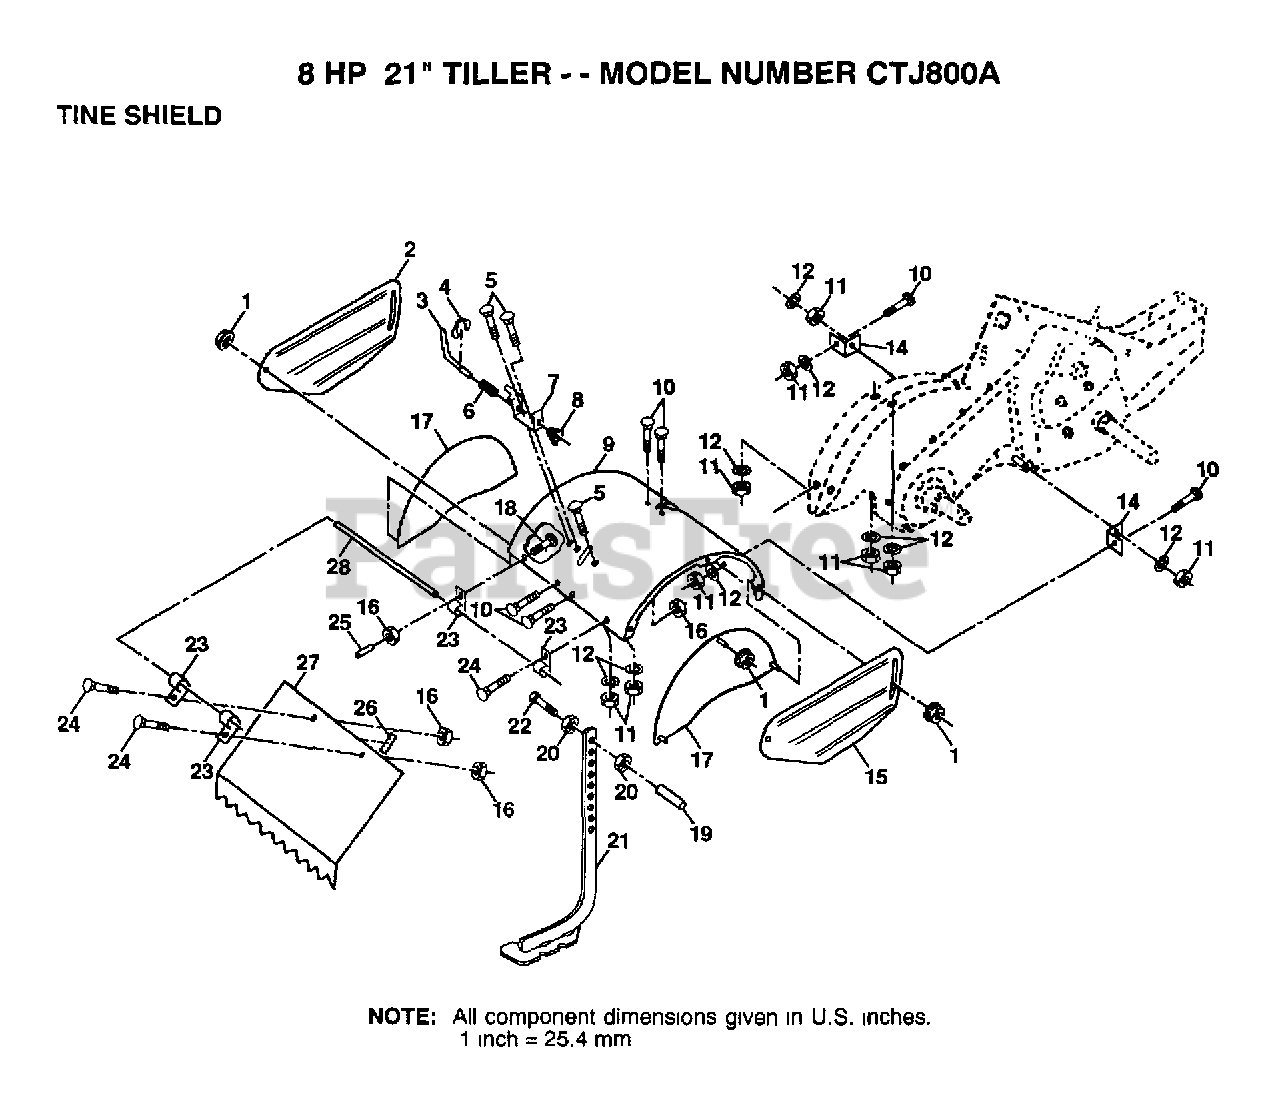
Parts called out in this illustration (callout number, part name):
1	NUT
2	SHIELD.LH.OUT.SID
3	STAKE PIN TI
4	KLIP RING TI
5	BOLT
6	SPRING TI
7	LATCH BRACKET TI
8	SPRING CRT
10	BOLT
11	NUT.HEX.5/16-18
12	LOCKWASHER
14	TINE SHLD BRKT TI
15	SHIELD.RH.OUT.SID
17	SHIELD.ASM.SIDE
18	BOLT
19	GRIP TI
20	NUT.HEX.3/8-16UNC
21	STAKE.ASM.DEPTH
23	HINGE CRT
24	BOLT.1/4-20X1/2
25	VINYL CAP TI
26	PAD IDLER TI
27	SHIELD.LEVELING
28	PIN.HINGE
